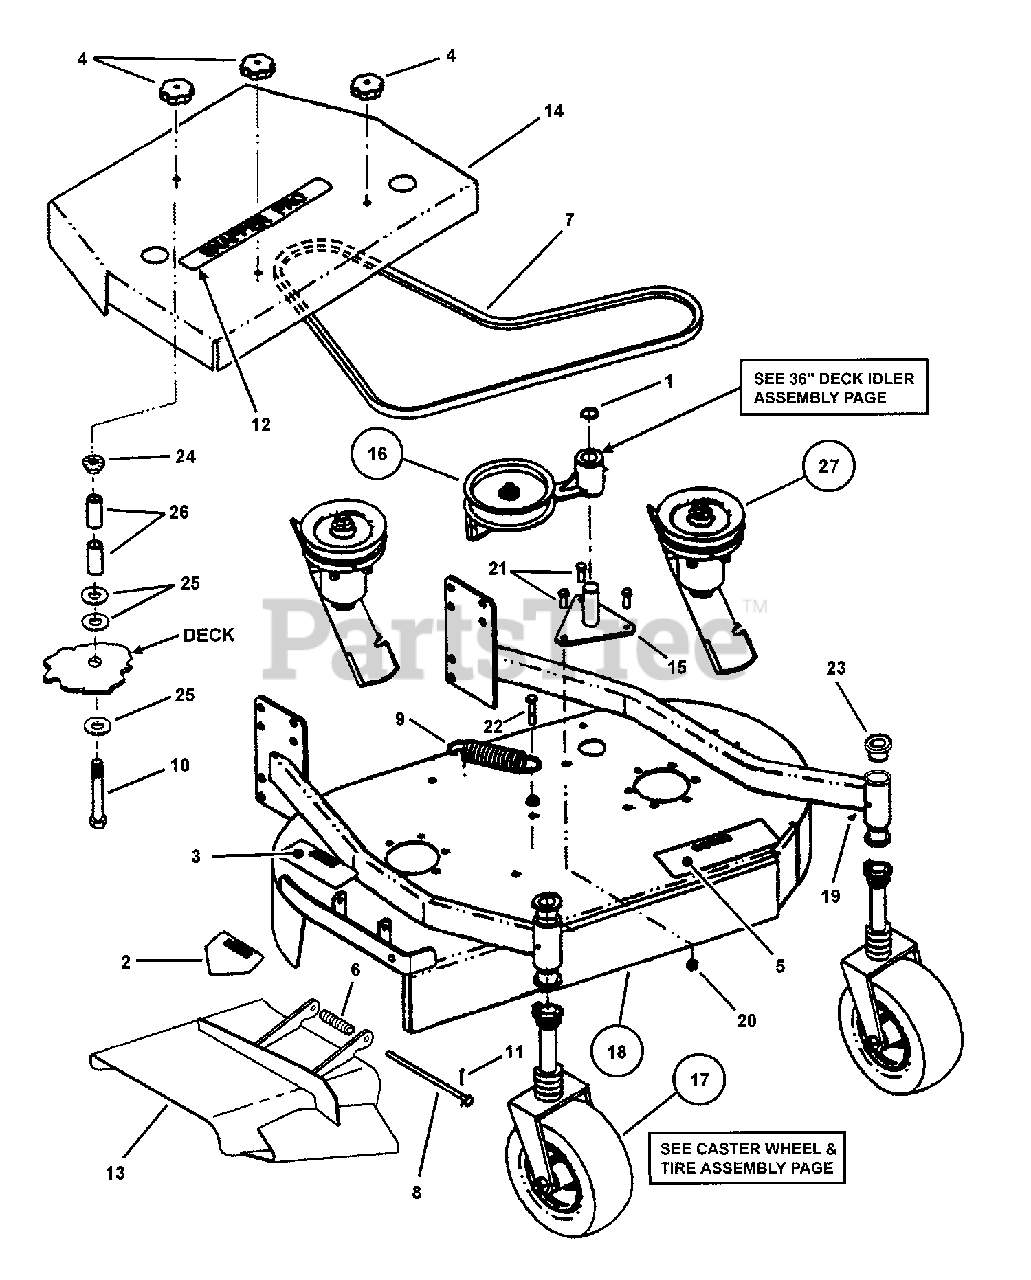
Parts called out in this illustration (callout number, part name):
1	RING, 1" External Retaining
2	DECAL, Warning (CPSC Cut Finger)
3	DECAL, Danger, Keep Hands and Feet Away
4	KNOB, Hood (5/16-18 thread)
5	DECAL, Caution- Operator Instruction
6	SPRING, Chute
7	* V-BELT, 36" Deck Drive (Nom. Effective Length: 84.80")
8	HINGE PIN, Chute
9	SPRING, Idler
10	SCREW, 5/16-18 x 4-1/2" Hex Head Cap, GR 5
11	COTTER PIN, 3/32 x 1"
12	DECAL, SNAPPER Pro w/Trademark
13	DEFLECTOR, 36" ANSI Compliant (Weldment)
14	COVER, 36"
15	PIVOT, Idler Arm (Weldment)
16	ASSEMBLY, Idler Arm, 36"
17	ASSEMBLY, Caster Red w/Gray Wheel
18	ASSEMBLY, 36" Deck, Fixed Height
19	LUBE FITTING, 1/4-28 Straight
20	NUT, 3/8-16 HEX NYLON LOCK
21	BOLT, 3/8-16 X 1" GD5 CZ
22	BOLT, 3/8-16 X 2, GD5, CZ
23	BUSHING, Caster
24	NUT, 5/16-18 Hex Flange Lock, GR 5
25	WASHER, 3/8" I.D. Flat
26	SPACER
27	ASSEMBLY, Spindle
